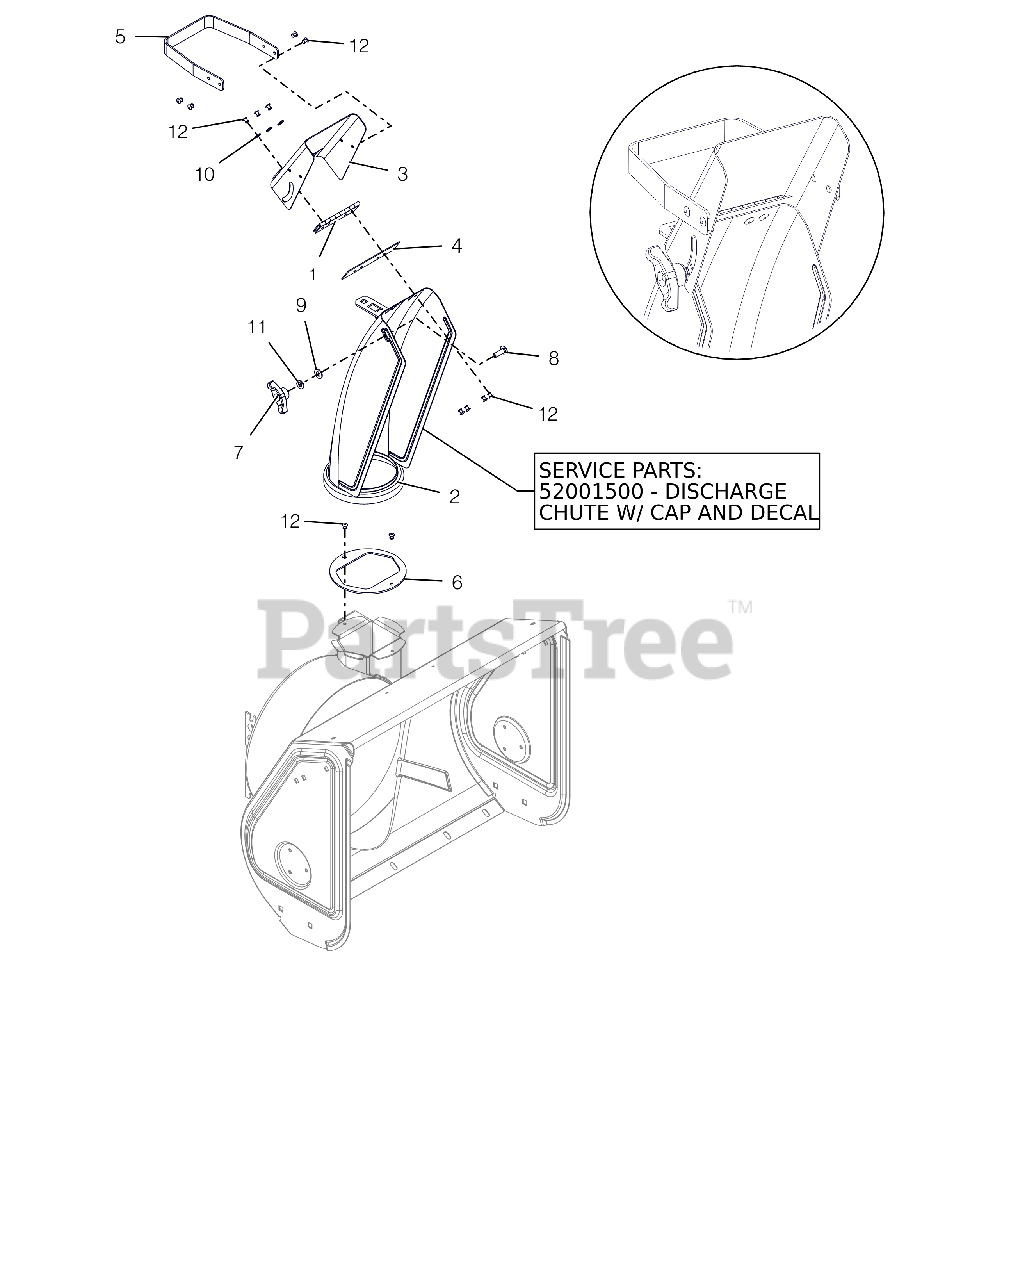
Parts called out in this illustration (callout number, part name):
2	CHUTE, COMPACT - TALL
2	CHUTE, DISCHARGE W/CAP & DECAL
3	CAP,MANUAL - COMPACT (W/DECAL)
4	CAP SEAL 5.25
5	HANDLE, DEFLECTOR
6	BAFFLE, COMPACT DISCHARGE
7	KNOB,WING .31-18 UNC NYL/TALC
8	@BLT-RHDSSQNK .31-18X1.00 G5YZ
9	WSHR-FL-NY .375X.75X.060
10	WSHR-FL-STL .196X.500X.06 YZ
11	@WSHR-FL-STL.344X.688X.065YWZC
12	RVT-POP .187 YZ
